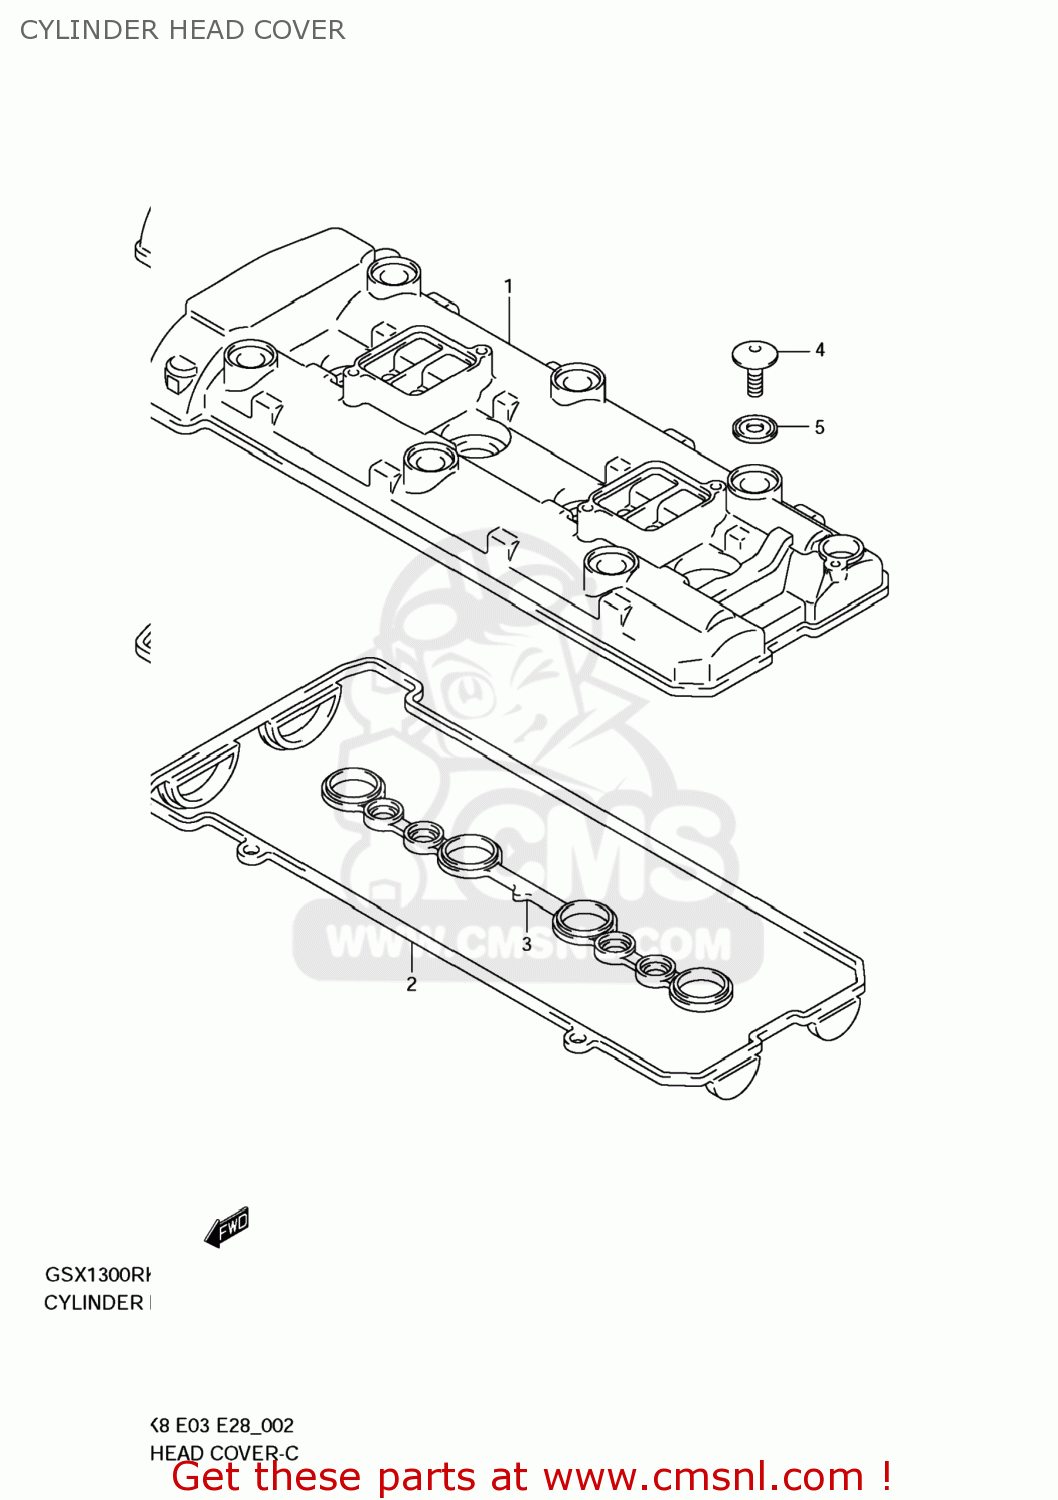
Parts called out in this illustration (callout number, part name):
1	COVER,CYLINDER HEAD
2	GASKET,CYL HEAD COVER NO.1 (NAS)
3	GASKET,CYL HEAD COVER NO.2 (NAS)
4	BOLT(7X17.5)
5	WASHER,CYL HEAD COVER
